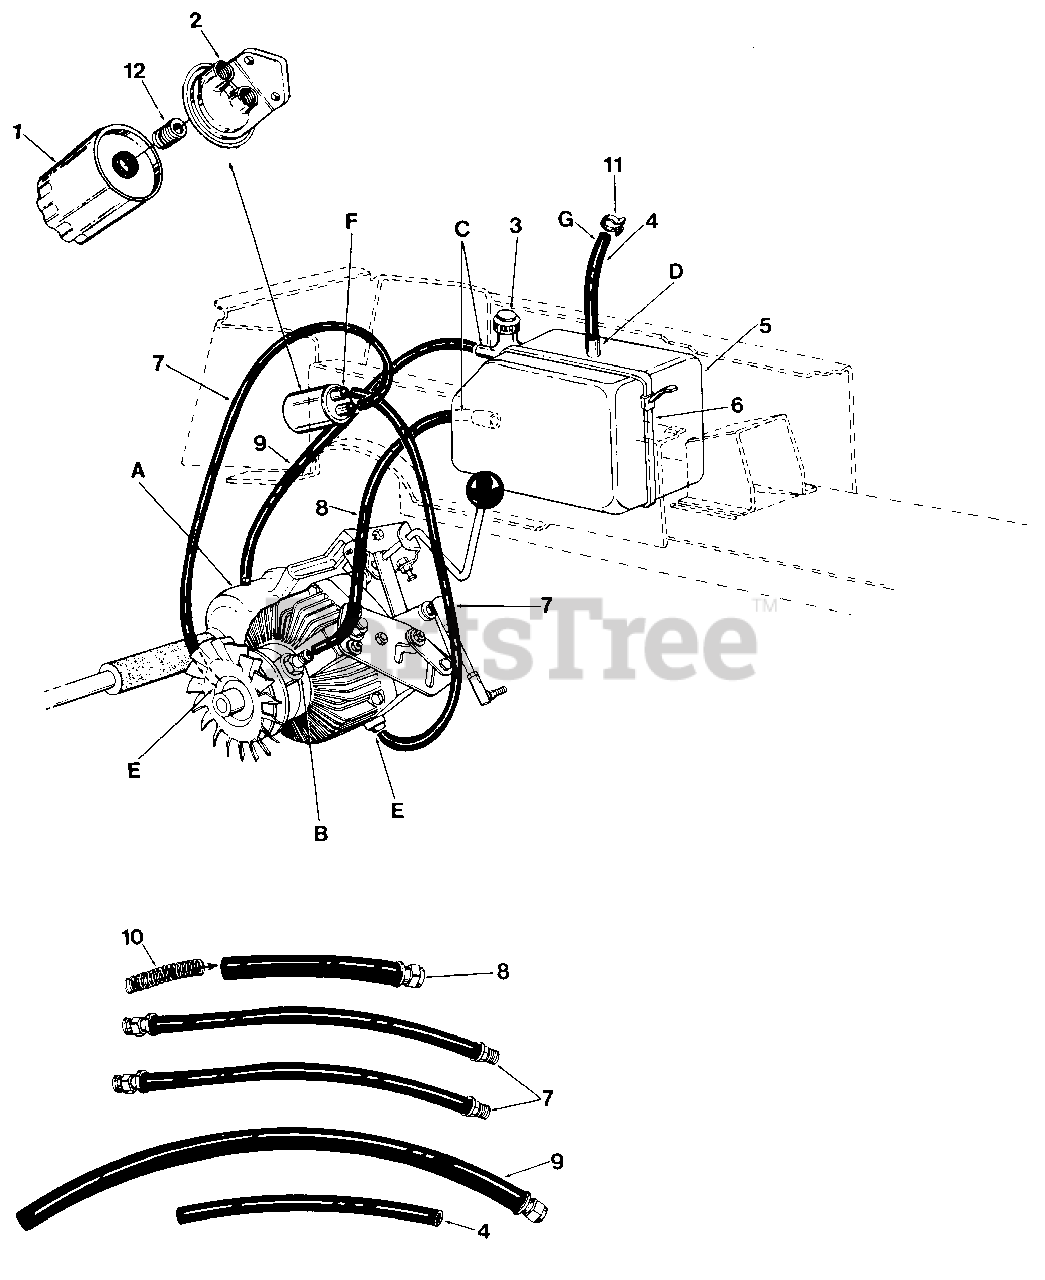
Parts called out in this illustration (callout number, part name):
1	Oil Filter
2	Filter Base
3	Oil Reservoir Cap
4	Gas Line 13" Lg.
5	Oil Reservoir
6	Cable Tie 34.25" Lg.
7	Hose Ass'y. 3/8" I.D. x 16.5" Lg.
8	Hose Ass'y. 518" I.D. x 9 Lg.
9	Hose Ass'y. 1/2" I.D.
11	Wire Retainer
12	Plug Expansion 13/16
